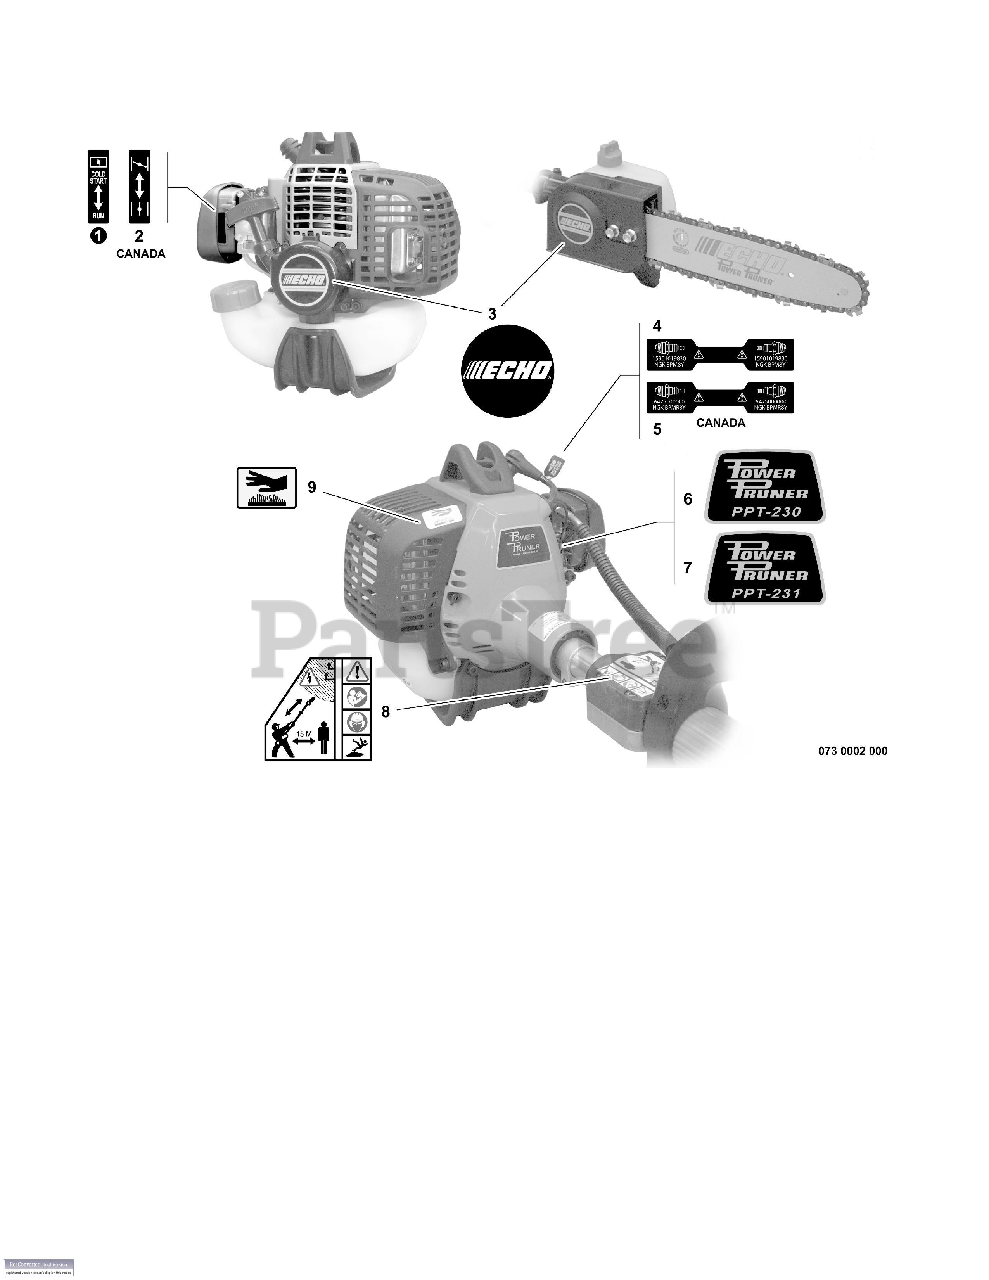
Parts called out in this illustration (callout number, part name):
1	LABEL - CHOKE
2	LABEL - CHOKE
3	LABEL - ECHO
4	LABEL - SPARK PLUG -- BPM-8Y
5	LABEL - SPARK PLUG -- BPMR-8Y
6	LABEL - MODEL PPT-230
7	LABEL - MODEL PPT-231
8	LABEL - CAUTION
9	LABEL - HOT SURFACE
